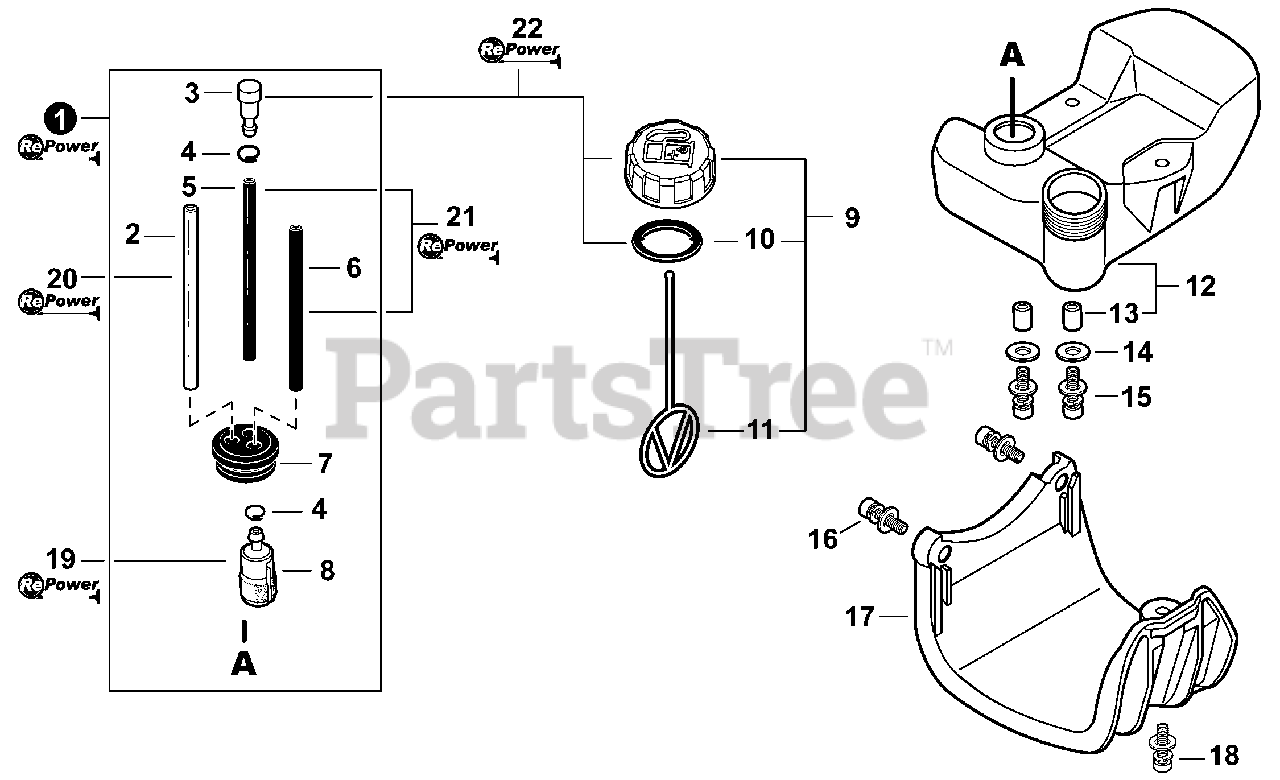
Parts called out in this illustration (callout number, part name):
1	FUEL SYSTEM KIT
2	PIPE, FUEL 3×6×80 CLEAR
3	VENT ASSY
4	CLIP 6.5 MM
5	PIPE 3×6×115 BLACK
6	PIPE, FUEL 3×6×170
7	GROMMET, FUEL
8	FILTER, FUEL
9	CAP ASSY, FUEL
10	GASKET, FUEL CAP
11	CONNECTOR, CAP L= 100 MM
12	TANK, FUEL
13	SPACER 6.2×7.8×6
14	WASHER 5.5×12×0.8
15	BOLT 5×16
16	BOLT 5×22
17	GUARD, FUEL TANK
18	SCREW 5×20
19	TUNE-UP KIT - REPOWER
20	BULK PIPE - 3×6 MM CLEAR (4 PIECES×2 M)
21	BULK PIPE - 3×6 MM BLACK (4 PIECES×2 M)
22	CAP/VENT KIT - REPOWER
